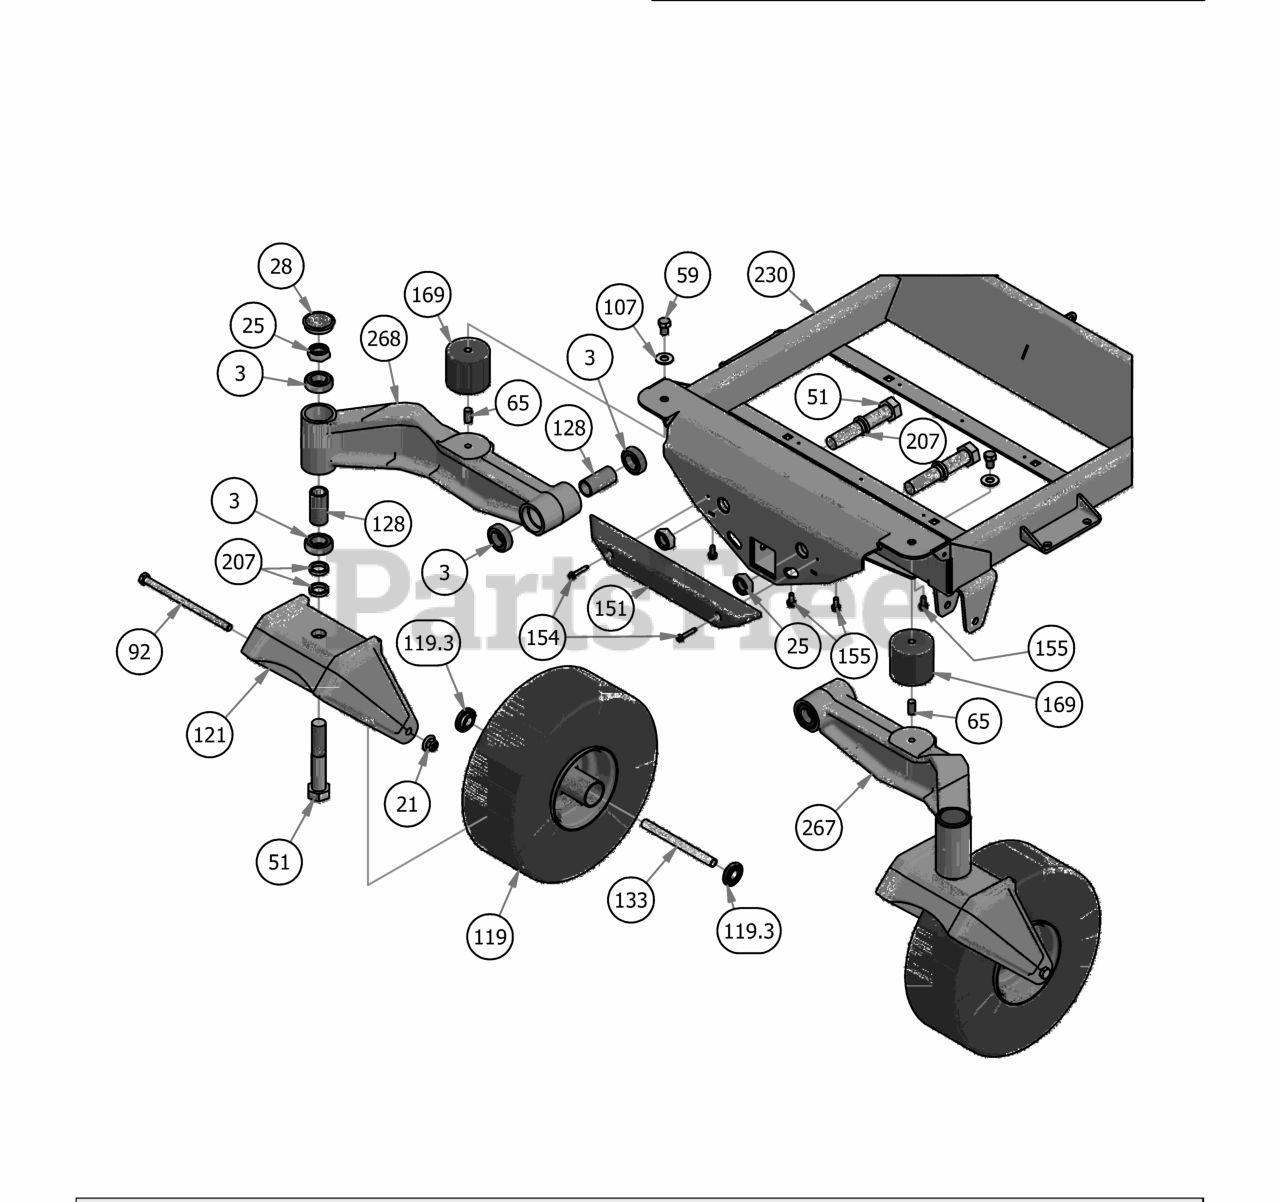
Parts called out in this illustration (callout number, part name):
3	Caster Bearing 2016 - 1641 Bearing
21	1/2-13 Nylon Flange Nut
25	1" Fine Thread 1/2 Nylock Nut
28	2017 Bearing Cover
51	1-14 x 5.5 Hex Bolt Grade 8 Zinc Yellow
59	1/2" x 3/4" Hex Bolt
65	1/2-13 x 1" Stud
92	1/2" x 9" GR 5 Hex Bolt
107	1/2" Washer (Grade 8)
119	2019 15x6.00-6 Non Pneumatic Black Front Assembly
119.3	1-3/4" Bearing-Large Bore Front Rim
121	2019 Rebel, Rogue, Renegade Front Fork
128	2016 Front Bearing Spacer
133	Front Wheel Spanner
151	2017 XP Bumper
154	1/4" x 1 1/2" Self Tapping Screw
155	5/16 x 3/4 washer head type F screw
169	Vibration Mount- Red Dot
207	Spacer, 1x1.375x.25
230	2019 Horizontal Diesel Frame
267	2019 Front I-Beam Left
268	2019 Front I-Beam Right
